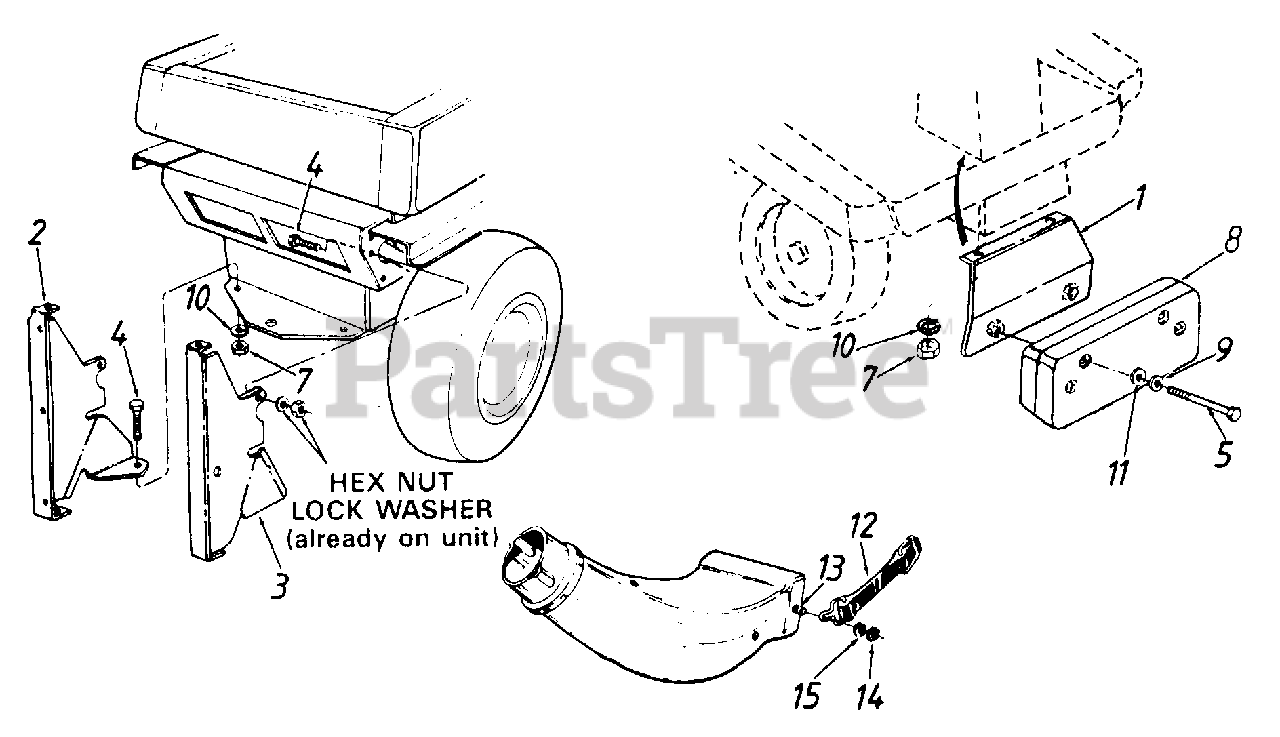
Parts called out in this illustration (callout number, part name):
1	BRACKET-SUPPORT
2	BRACKET-SUPPORT-RH
3	BRACKET-SUPPORT-LH
4	SCREW-HEX 5/16-18 x 1.00
5	SCREW-HEX 3/8 x 4.5 N.C GR. 5
7	NUT-HEX 5/16-18
8	COUNTERWEIGHT
9	WASHER-BELL .400 ID x .88 x .060
10	WASHER-LOCK-5/16
11	WASHER-FL
12	STRAP ASSY-RETAINER
13	SCREW-HEX 1/4-20 C .62
14	NUT-INS LOCK 1/4-20
15	WASHER-SPRING.270 ID X.51 OD X.030
